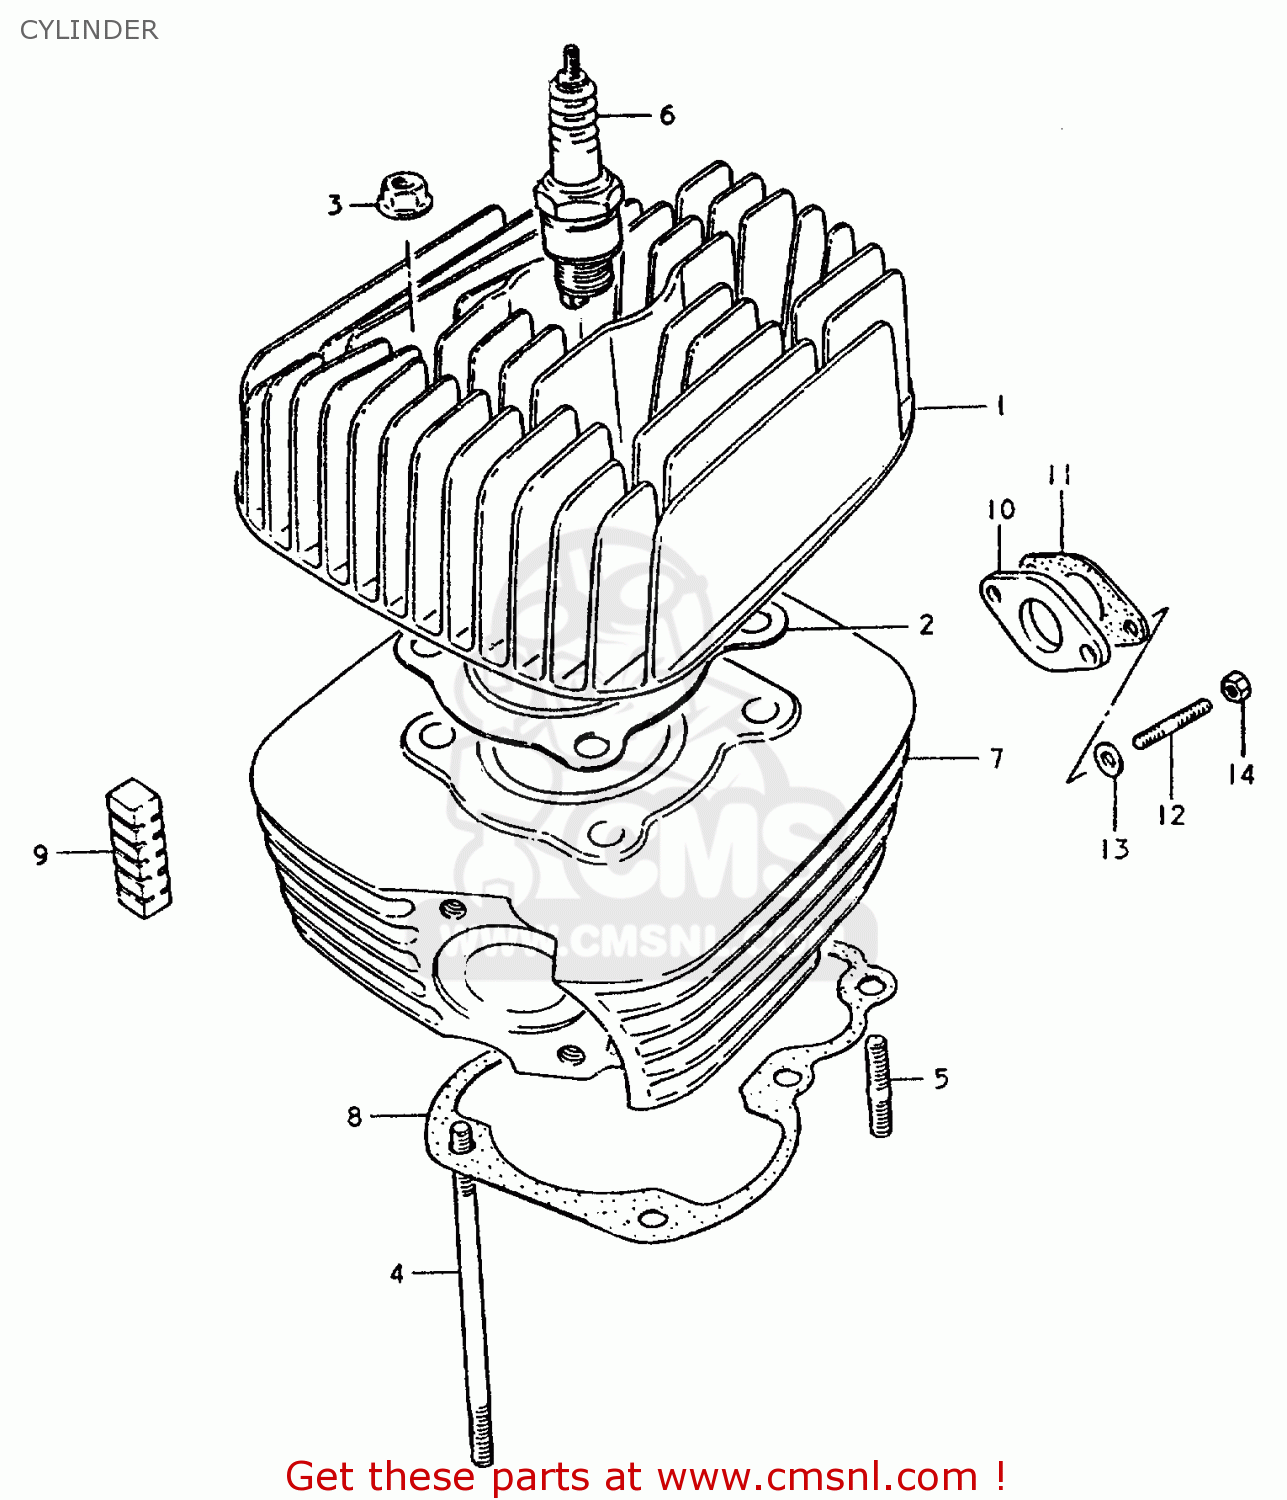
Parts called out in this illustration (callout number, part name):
1	CYLINDER HEAD
2	GASKET,CYLINDER HEAD (NAS)
3	NUT
4	BOLT,STUD
5	STUD 6X16
6	SPARK PLUG (ND,W20EP)
7	CYLINDER
8	GASKET,CYLINDER (MCA)
9	PAD,CYLINDER
10	INSULATOR,CARBURETOR
11	GASKET,CARBURETOR (MCA)
12	STUD BOLT
13	WASHER
14	NUT
